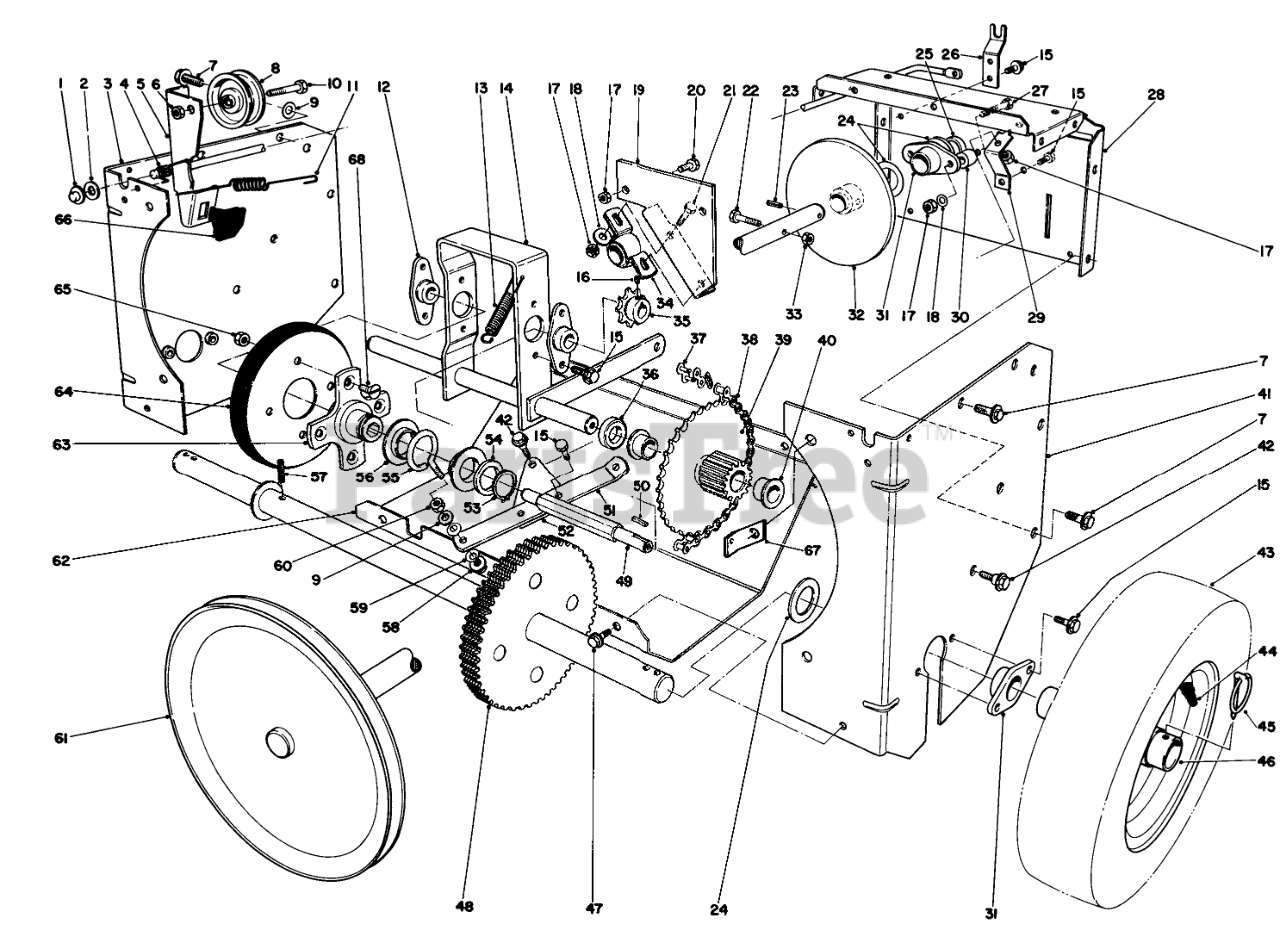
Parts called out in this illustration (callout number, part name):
1	PUSH NUT
2	WASHER-FLAT
3	RH TRACT SIDE PLT R
4	TORSION CLUTCH SPRING
5	Clutch Rod (Incl. Ref. #66)
6	NUT-LOCK, NI
7	SCREW-HWHTF
8	PULLEY-IDLER
9	WASHER-FLAT
10	SCREW-HH
11	SPRING
12	BEARING-WHEEL, FRICTION
13	TENSION SPRING
14	PIVOT SHAFT WA B
15	SCREW-HWHTF
16	SCREW-HSH
17	NUT-LOCK, NI
18	WASHER-PLAIN
19	SHAFT SUPT BRKT B
20	SCREW-HH
21	SCREW-HH
22	SCREW-HH
23	PIN-ROLL, SLOTTED
24	WASHER
25	DRIVE SHAFT SPACER
26	CLUTCH ROD SUPPORT
27	SCREW-HH
28	CENTER FRAME R
29	PIVOT BRACKET
30	BRG STANDOFF
31	AXLE BEARING
32	FRICTION PLT WA
33	NUT-LOCK, CONE
34	PILLOW BLOCK BRG
35	SPROCKET
36	COSHAFT SPACER
37	LINK-CONNECTING
38	ROLLER-CHAIN
39	Gear & Bushing (Incl. Ref. #40)
40	BUSHING
41	LH TRACT SIDE PLT R
42	SHOULDER SCREW
44	TUBE-INNER
45	PIN-LYNCH
46	WHEEL
47	SCREW-HWH
48	AXLE & GEAR WA
49	FRICTION WHL SHAFT
51	SHIFT LINKAGE
52	PIVOT PLATE
53	RING-RETAINING
54	WASHER-THRUST
55	SLIDER RING COLLAR
56	SLIDER RING
57	PIN-ROLL, SLOTTED
58	NUT-LOCK, FLANGE
59	WASHER-SPRING
60	NUT-LOCK
61	PULLEY/SHFT WA
62	LOWER SHIELD R
63	TRACTION DISC HUB
64	FRICTION WHEEL
65	NUT-LOCK, NI
66	PAD-BRAKE
67	SPRING BRACKET
68	5/16-18X5/8 FLT HD MS
